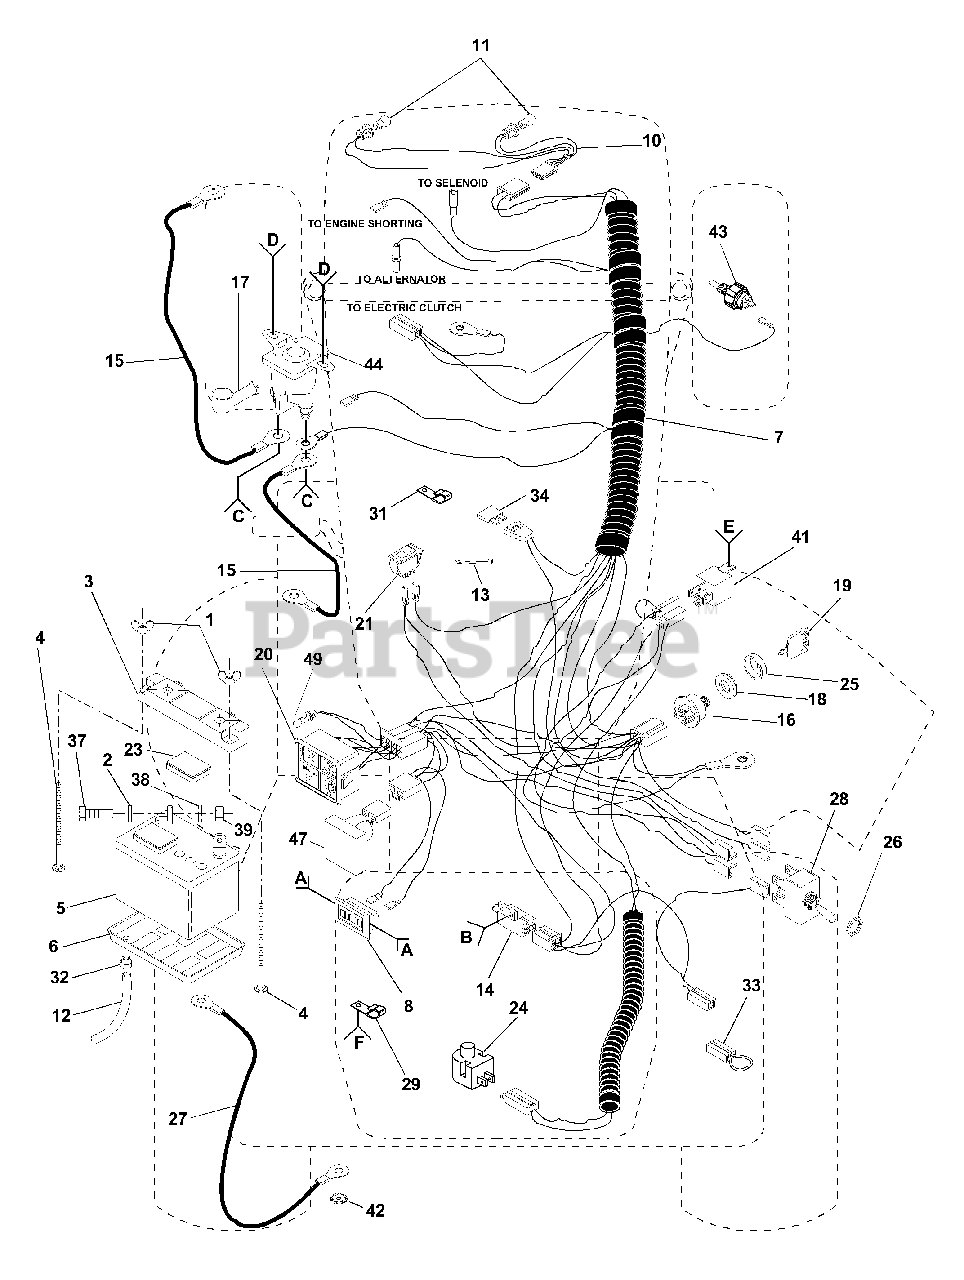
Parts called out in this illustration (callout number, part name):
1	Nut, Wing 1/4-20
2	Washer 9/32 x 5/8 x 16 Gauge
3	Guard, Terminal
4	Bolt, Carriage 1/4-20 x 7-1/2
5	Battery
6	Tray, Battery
7	Harness, Ignition
8	Meter, Hour
9	Screw #10-24 x 1/2
10	Harness, Socket Light
11	Bulb, Light
12	Tube, Tray Battery
13	Tie, Cable
14	Switch, Interlock (Clutch)
15	Cable, Battery
16	Switch, Ignition
17	Cover, Terminal
18	Nut, Ignition
19	Key, Molded
20	Package, Light
21	Switch, Light
22	Nut, Crownlock 1/4-20
23	Caps, Battery
24	Switch, Plunger
25	Bezel, Ignition
26	Nut, Hex
27	Cable, Battery
28	Switch, PTO
29	Clip, Insulated
30	Screw, Hex, Tap #10-24 UNC
31	Clip, Line Fuel
32	Clamp, Hose
33	Loop, Wire
35	Bolt, Hex 1/4-20 x 1/2 Grade 5
36	Nut, Hex, Keps 1/4-20
37	Bolt, Hex 1/4-20 x 3/4
38	Washer, Lock 1/4
39	Nut, Hex 1/4-20
40	Washer, Lock, External Tooth 1/4
42	Washer, Lock, External Tooth 3/8
43	Switch, Oil Sensor
44	Solenoid
45	Washer, Lock 1/4
46	Nut, Hex, Jam 1/4-20
47	Sensor, Low Voltage
48	Screw, Hex Washer Thrd. Cut 1/4-20 x 1/2
49	Bulb, Light Package
